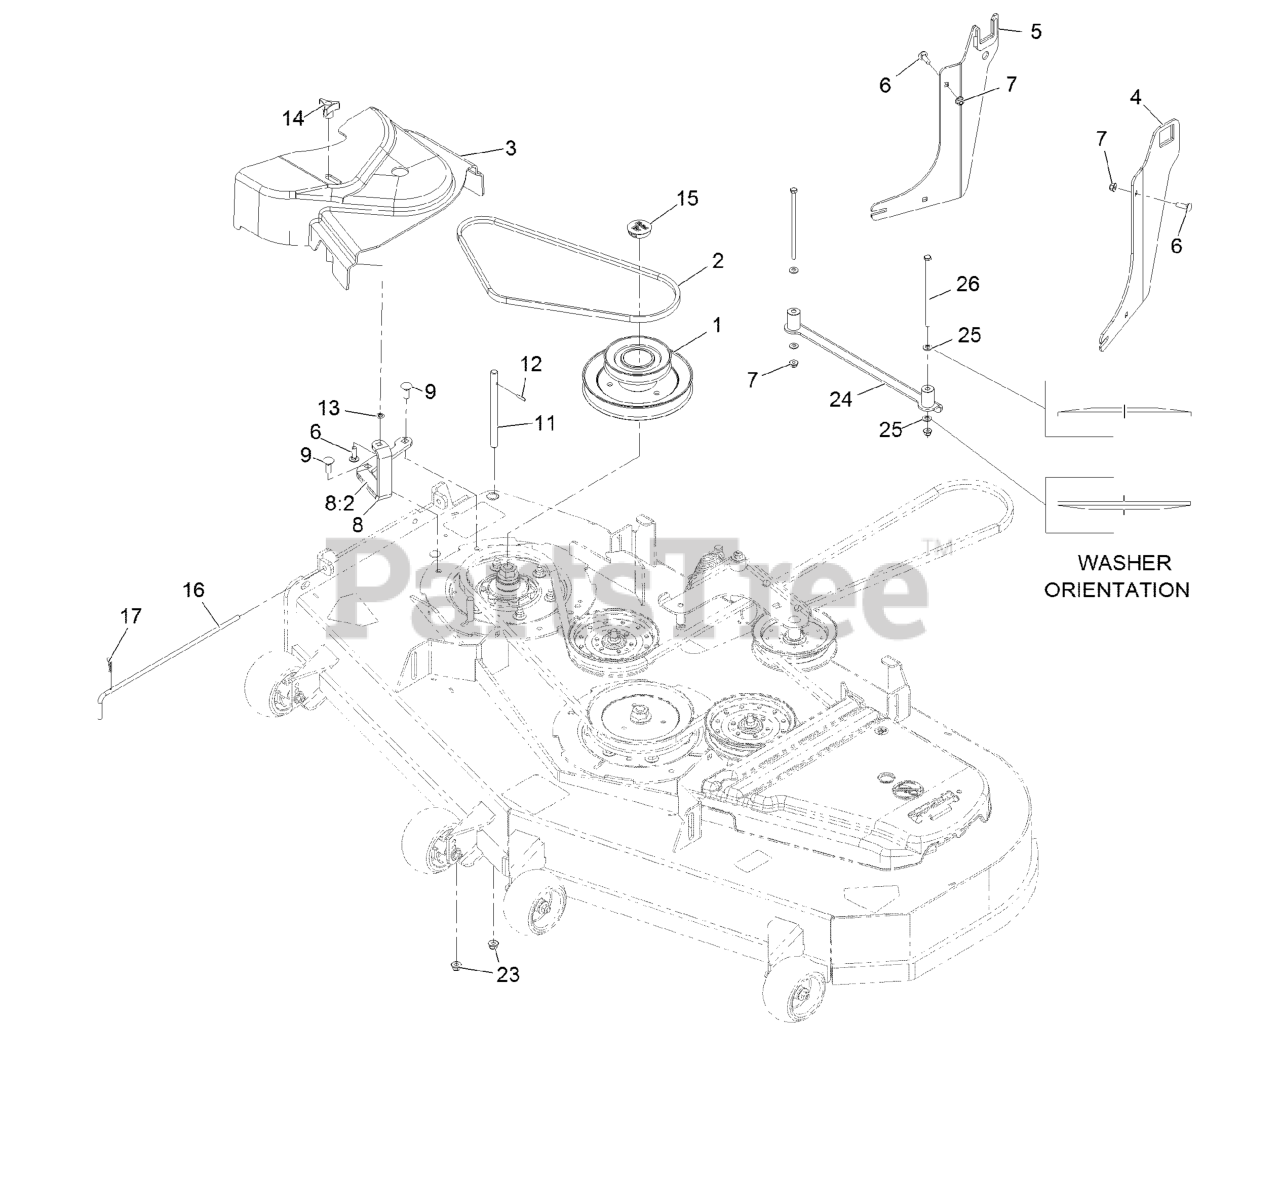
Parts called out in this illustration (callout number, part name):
1	JACKSHAFT,UV DRIVE 604 SPLINED
3	COVER-BELT UVE 60
4	BRACKET ASM, LH
5	BRACKET ASM, RH
6	BOLT-CARR
7	NUT-HF, NI
8	ASM-CVR BRKT W/DECAL
8:2	DECAL-COVER, MISSING
9	BOLT-CARR
11	SHAFT-CATCHER, GRASS
12	PIN-ROLL
13	RING-RETAINING, BOLT
14	KNOB-3 PRONG
15	PLUG, BLACK NYLON 1.75
16	PIN,CHUTE PIVOT
17	PIN-COTTER
23	Nut-Nyloc 3/8-16 Flg
24	ASM-HYDRO GUSSET
25	WASHER-SPRING
26	SCREW HH
